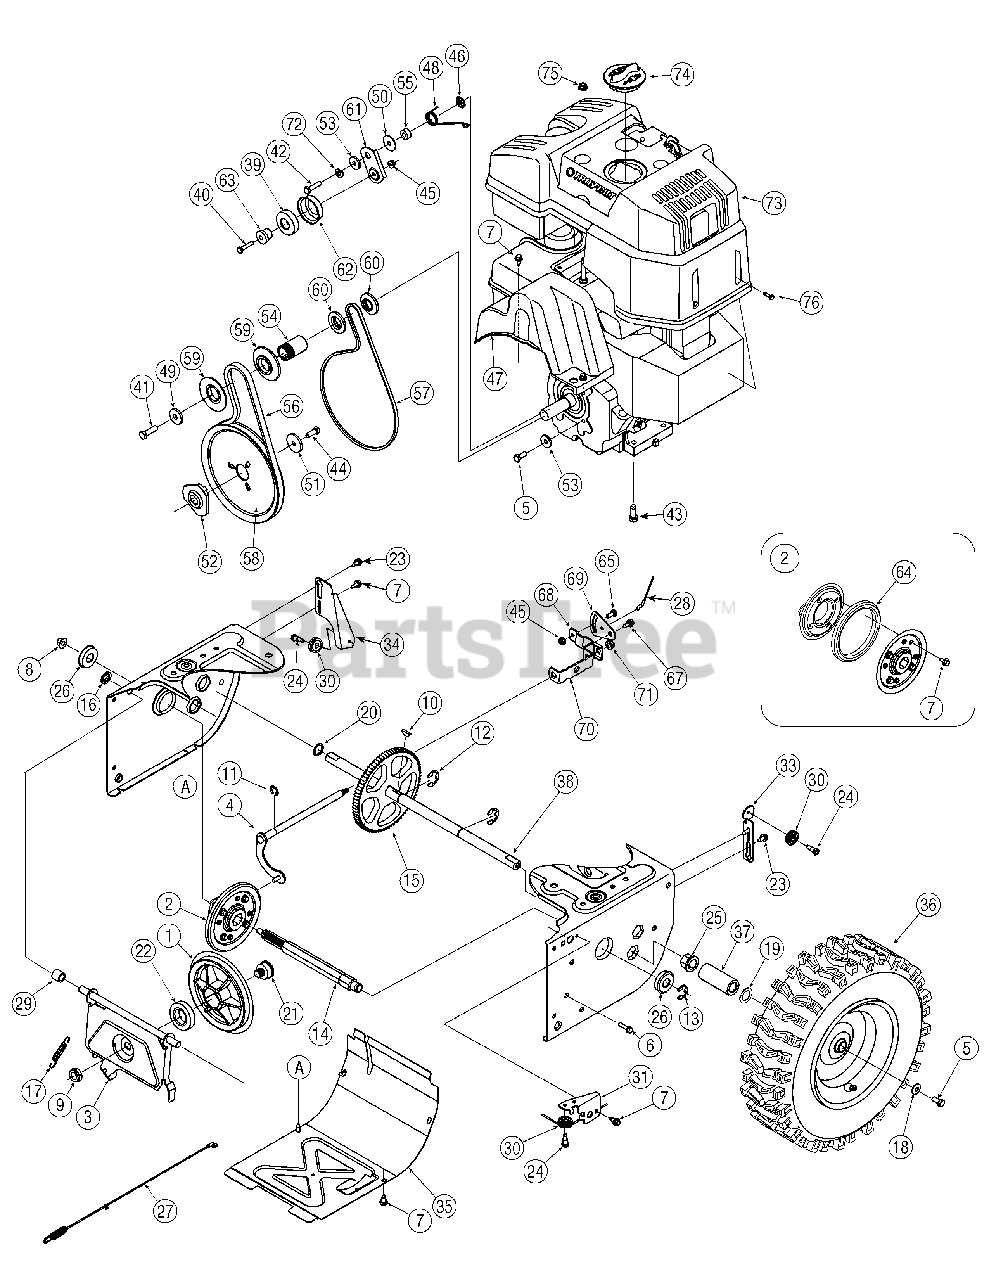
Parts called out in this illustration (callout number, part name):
1	Disc, Friction Wheel
2	Friction Wheel Assembly, 5.5
4	Shift Assembly, Rod
5	Hex Screw, 5/16-24, .750, Gr5
6	Screw, 1/4-20, 1.000
7	Screw, 1/4-14 x .625
8	Nut, Flange Lock, 3/8-16, Nylon
9	Nut, Jam Lock, 5/8-18, Gr5, Nylon
10	Key, Hi Pro, 3/16 x 3/4 Dia.
11	E-ring, .500 Dia.
12	E-ring, Retaining, .875 Dia.
13	E-ring, .750 Dia.
14	Hex Shaft, .8125, 7-Tooth
15	Gear, 80-Tooth
16	Speed Nut, .500
17	Extension Spring
18	Washer, Bell, .340 x .872 x .060
19	Washer, Flat, .793 x 1.24 x .060
20	Washer, Flat, .75 x 1.00 x .060
21	Pin, Friction Disc
22	Ball Bearing, 30 x 55 x 13
23	Screw, Shoulder, .37 x .105, 1/4 -20
24	Screw, 1/4-28, .375
25	Bearing, Hex Flange x .75 ID
26	Bearing, Ball, 17 x 40 x 12
27	Clutch Cable, Wheel, 44.95"
28	Clutch Cable, Auger, 47.23"
29	Spacer, .508 ID x .75 OD x .68
30	Roller, Cable
37	Spacer, 1.25 x .75 x 3.0
38	Axle, .75 x 22"
39	Ball Bearing
40	Hex Screw, 1/4-20, 1.25, Gr5
41	Hex Screw, 3/8-24, 1.25, Gr8
42	Hex Screw, 5/16-24, 1.25, Gr5
43	Screw, Sems, 3/8-16, 1.00
44	Hex Screw, 5/16-24, .875, Gr8
45	Nut, Flange Lock, 1/4-20, Nylon
46	Nut, Push-on, .25 Dia.
47	Cover, Belt
48	Spring, Torsion, .850 ID x .354
49	Washer, Flat, .406 x 1.25 x .157
50	Washer, Flat, .330 x 1.25 x.06
51	Washer, Flat, .34 x 1.50 x .150
52	Pulley, Adapter, .75 Dia.
53	Spacer, Shoulder
54	Spacer, .875 ID x 1.185
55	Spacer, .340 x .750 x .360
56	Belt, Auger Drive
57	Belt, Wheel Drive 3/8"
58	Pulley, Auger Drive, 8.1 x .5
59	Pulley, Half, 2.6 OD
60	Pulley, Half, 1.5 OD
61	Idler Bracket, Wheel Drive
62	Sleeve, Bearing Idler
63	Spacer, Shoulder, .26 x .79 x .538
64	Rubber, Friction Wheel, 5.5 OD
65	Hex Screw, 1/4-20, .620, Gr5
67	Screw, Shoulder, .37 x .105, 1/4 -20
68	Bracket, Shift Spacer
71	Nut, Flange Lock, 5/16-18, Nylon
72	Washer, Lock, 5/16
73	Engine Shroud, Troy-Bilt
74	Cap, Spark Plug Access
75	Nut, Flange Lock, 5/16-18, Gr5
76	Screw, #10-16, .75
